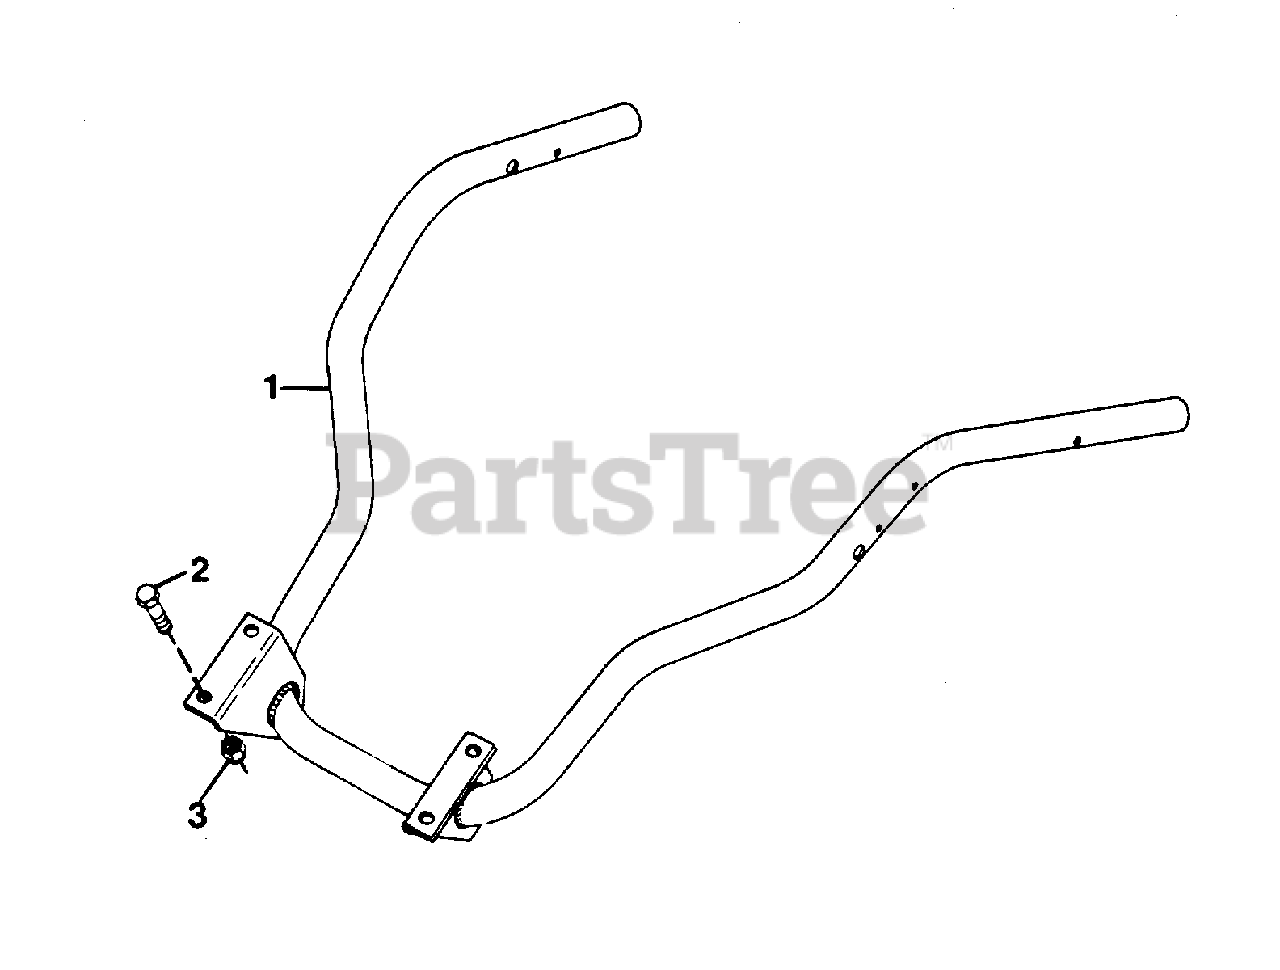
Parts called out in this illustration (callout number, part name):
1	WELDMENT, HANDLEBAR
2	BOLT, HEX 3/8-16X1.25 GR. 8
3	NUT, LOCK 3/8-16
